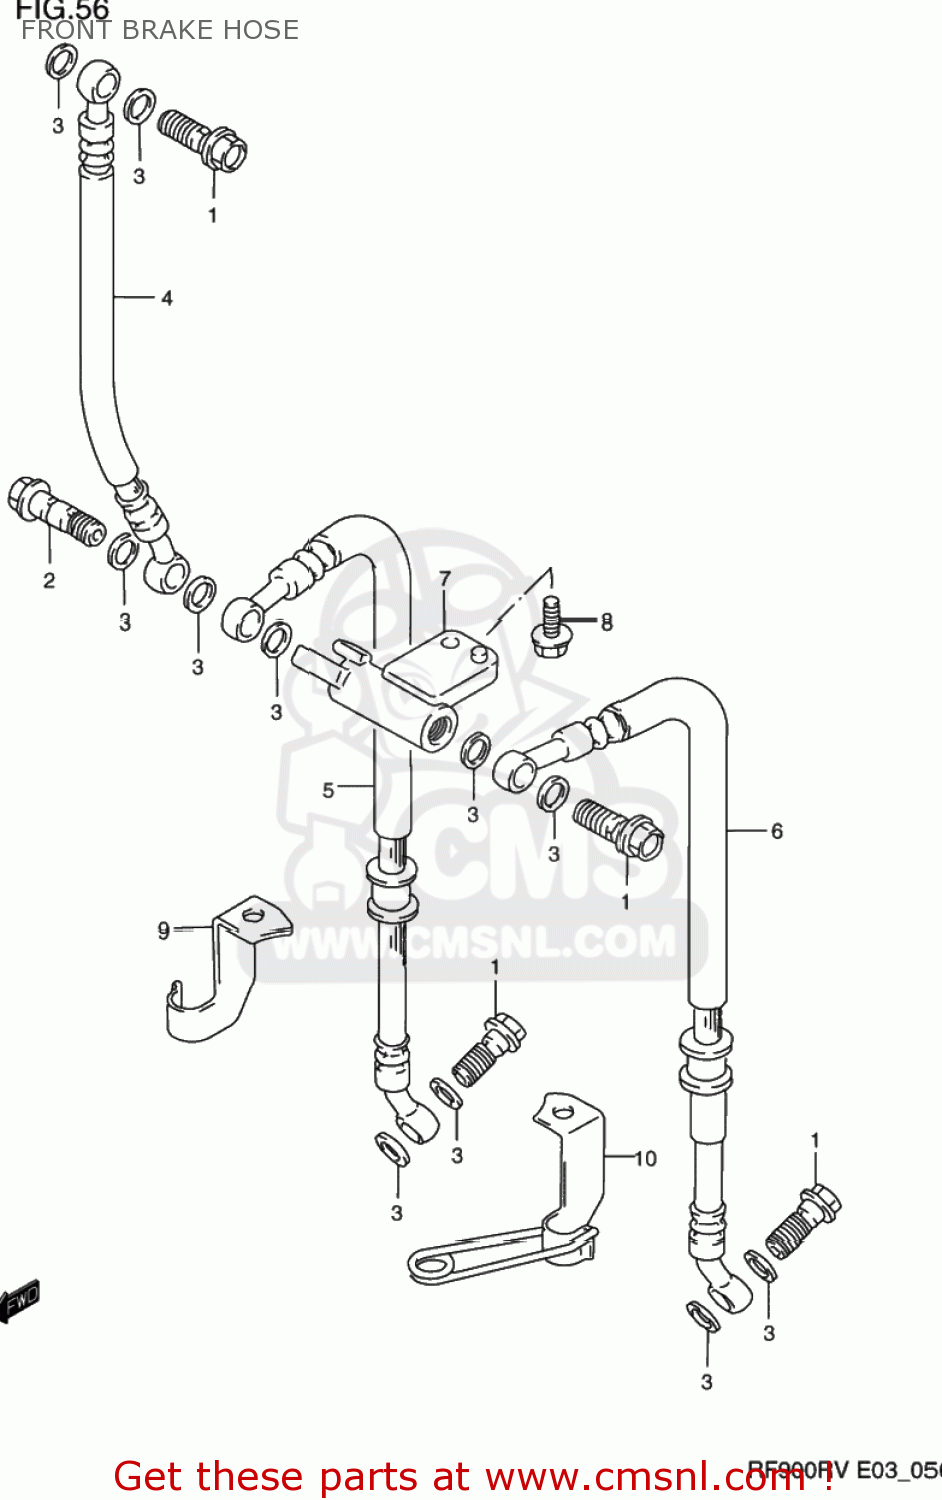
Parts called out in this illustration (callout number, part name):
1	BOLT UNION
2	BOLT UNION
3	WASHER(10X15X1.5)
4	HOSE,FR BRAKE NO.1
5	HOSE,FR BRAKE NO.2,R
6	HOSE,FR BRAKE NO.2,L
7	JOINT,BRAKE HOSE
8	BOLT
9	CLAMP,FR BRAKE HOSE,R
10	CLAMP COMP,FRONT BRAKE
